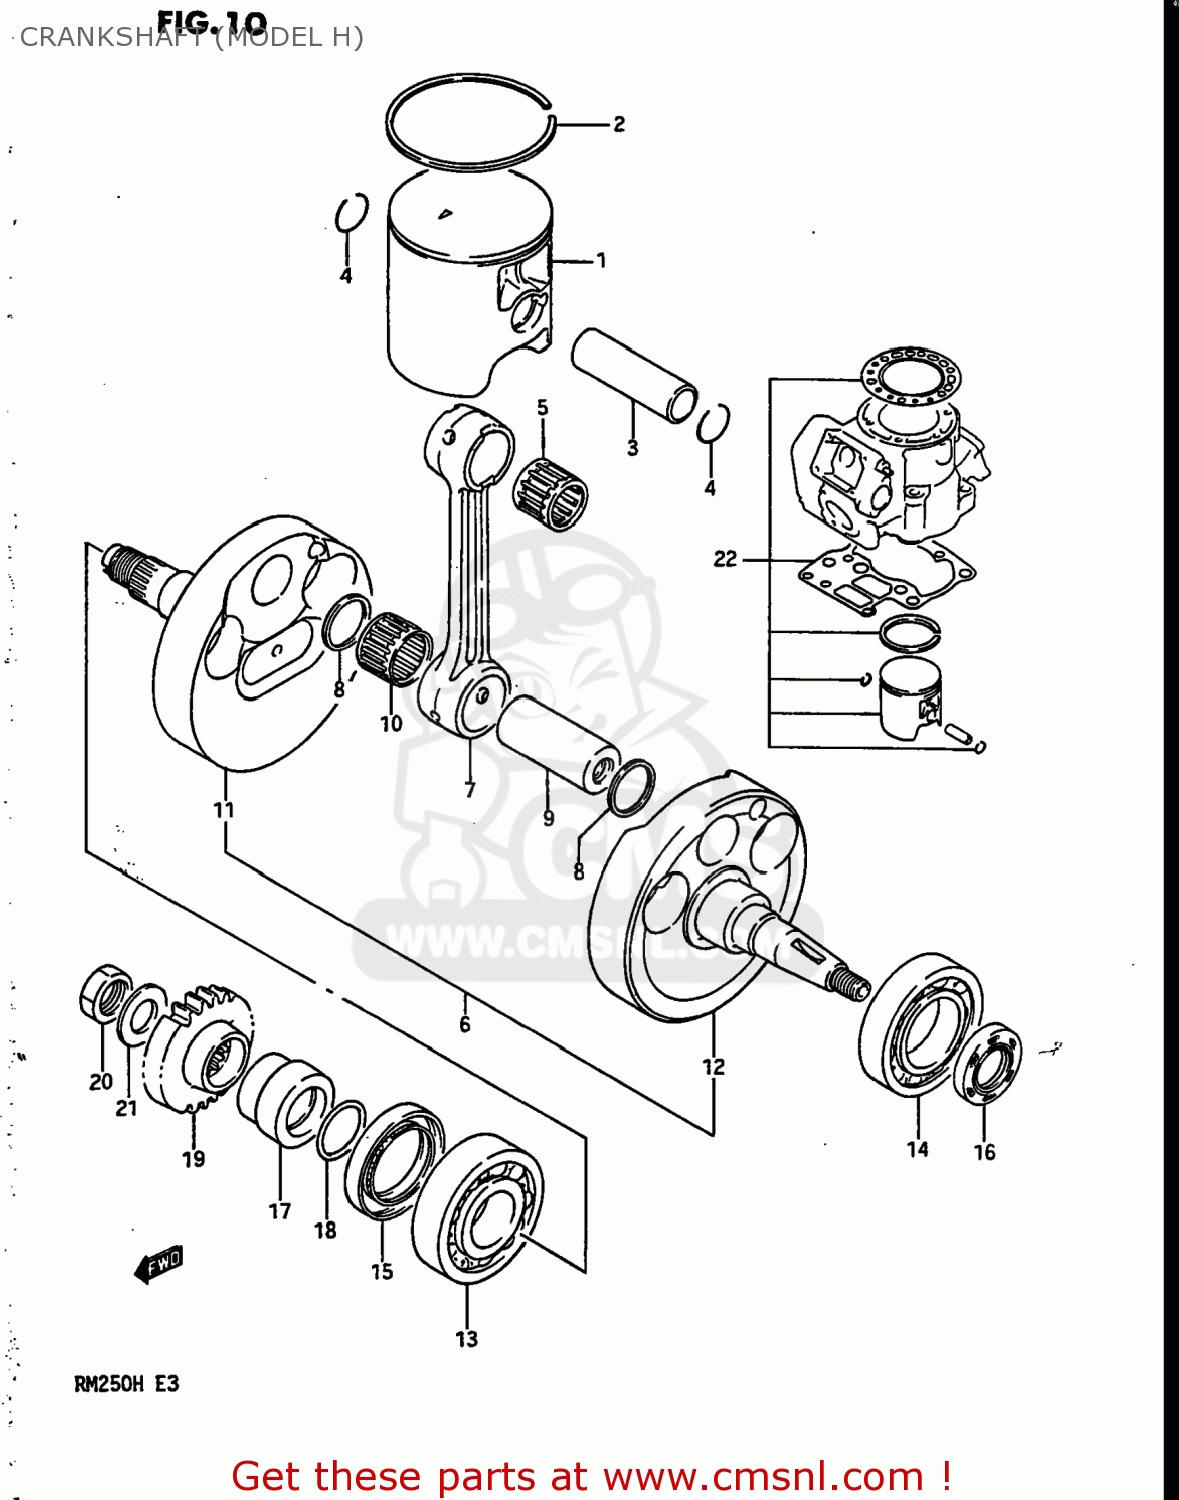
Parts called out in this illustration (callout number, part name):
1	PISTON (67.00MM)
2	RING,PISTON
3	PIN,PISTON
4	CIRCLIP
5	BEARING(18X23X22)
6	CRANKSHAFT ASSEMBLY
7	CONNECTION ROD
8	WASHER(24X29X1.5)
9	PIN COMP,CRANK
10	BEARING
11	CRANKSHAFT,R
12	CRANKSHAFT,LEFT
13	BEARING(25X62X17)
14	BEARING(30X62X16)
15	SEAL,OIL(36X52X8)
16	OIL SEAL
17	SPACER,PRIMARY DRIVE GEAR
18	O RING(D:2.4,ID:21.8)
19	GEAR,PRIMARY DRIVE
20	NUT
21	WASHER
22	PISTON SET (STD)
